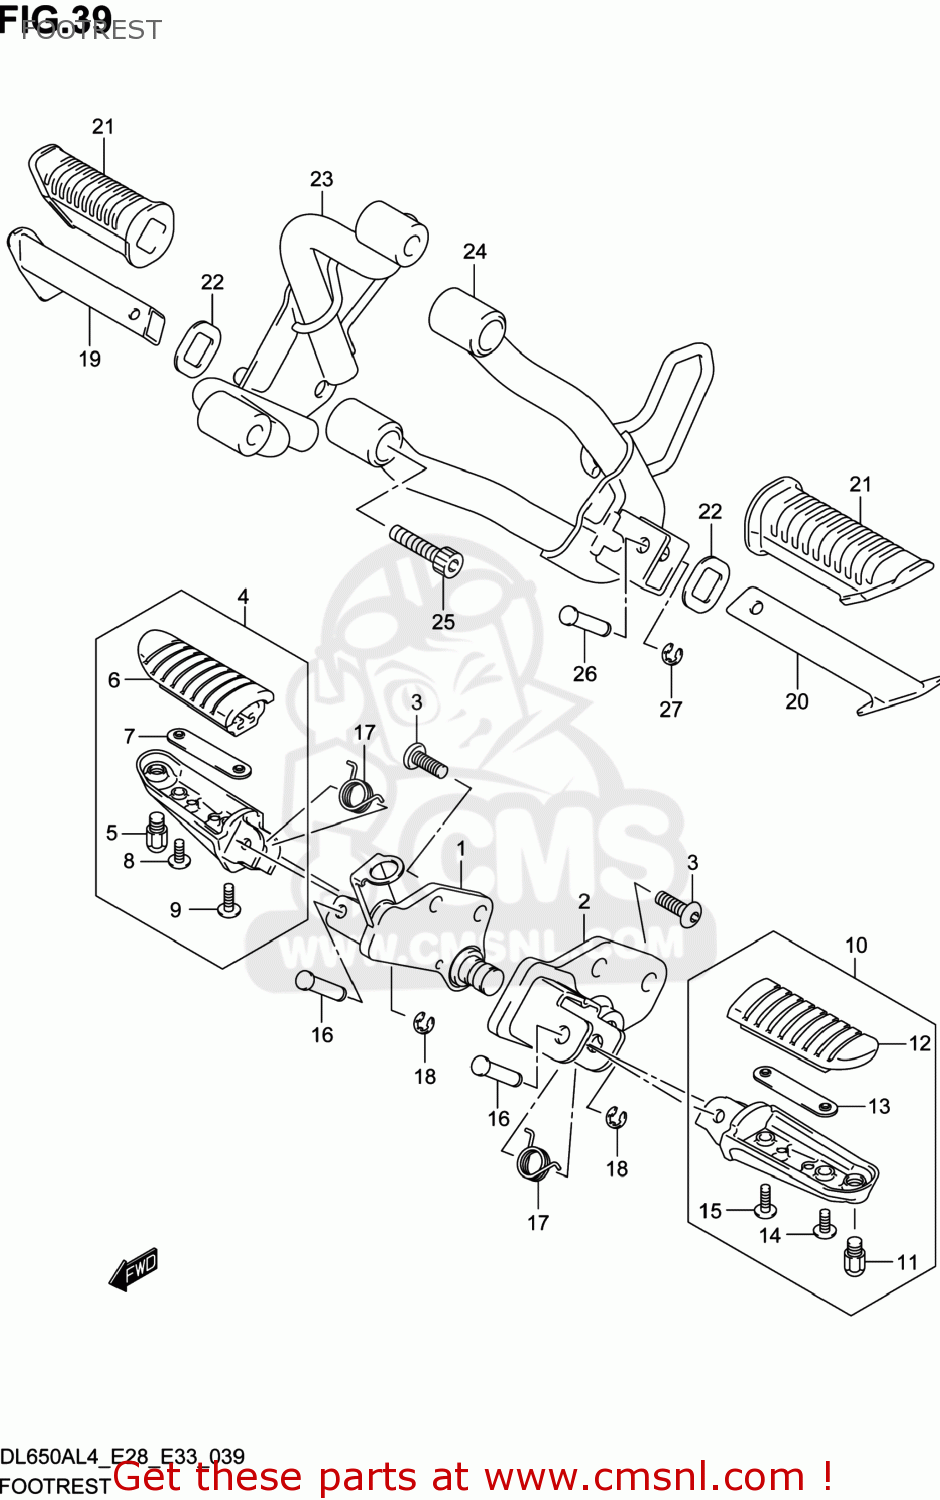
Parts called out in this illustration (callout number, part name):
1	BRACKET,FR FOOTREST,R
2	BRACKET,FR FOOTREST,L
3	BOLT(8X23)
4	FOOTREST ASSY,PILLION,R
5	BOLT,BANK SENSOR
6	RUBBER,FOOTREST
7	PLATE,FR FOOTREST RUBBER
8	SCREW
9	SCREW
10	FOOTREST ASSY,PILLION,L
11	BOLT,BANK SENSOR
12	RUBBER,FOOTREST
13	PLATE,FR FOOTREST RUBBER
14	SCREW
15	SCREW
16	PIN(8X33.2)
17	SPRING
18	E RING
19	BAR,PILLION FOOTREST,R
20	BAR,PILLION FOOTREST,L
21	RUBBER,PILLION FOOTREST
22	WASHER,FOOTREST RUBBER
23	BRACKET,PILLION FOOTREST,R
24	BRACKET,PILLION FOOTREST,L(BLA
25	BOLT(8X40)
26	PIN(6X29.5)
27	E RING
